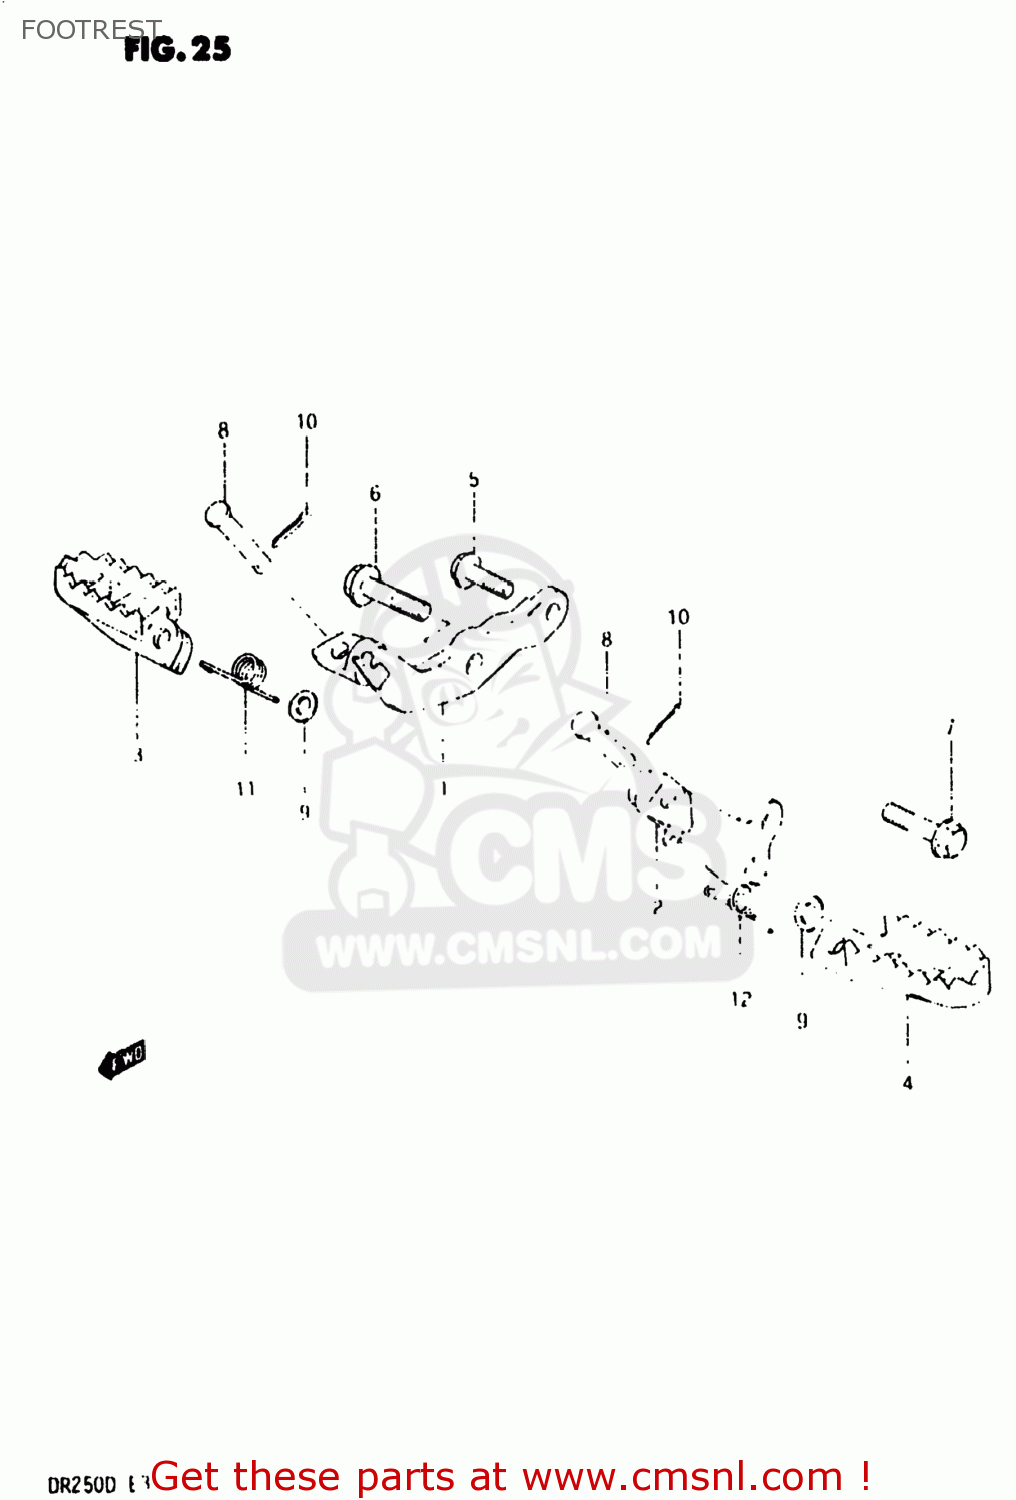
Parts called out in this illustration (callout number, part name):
1	BAR,FRONT FOOTREST
2	BAR,FRONT FOOTREST,LEFT
3	FOOTREST,RIGHT
4	FOOTREST
5	BOLT
6	BOLT, RH
7	BOLT
8	PIN
9	WASHER
10	PIN 20X20
11	SPRING
12	SPRING
